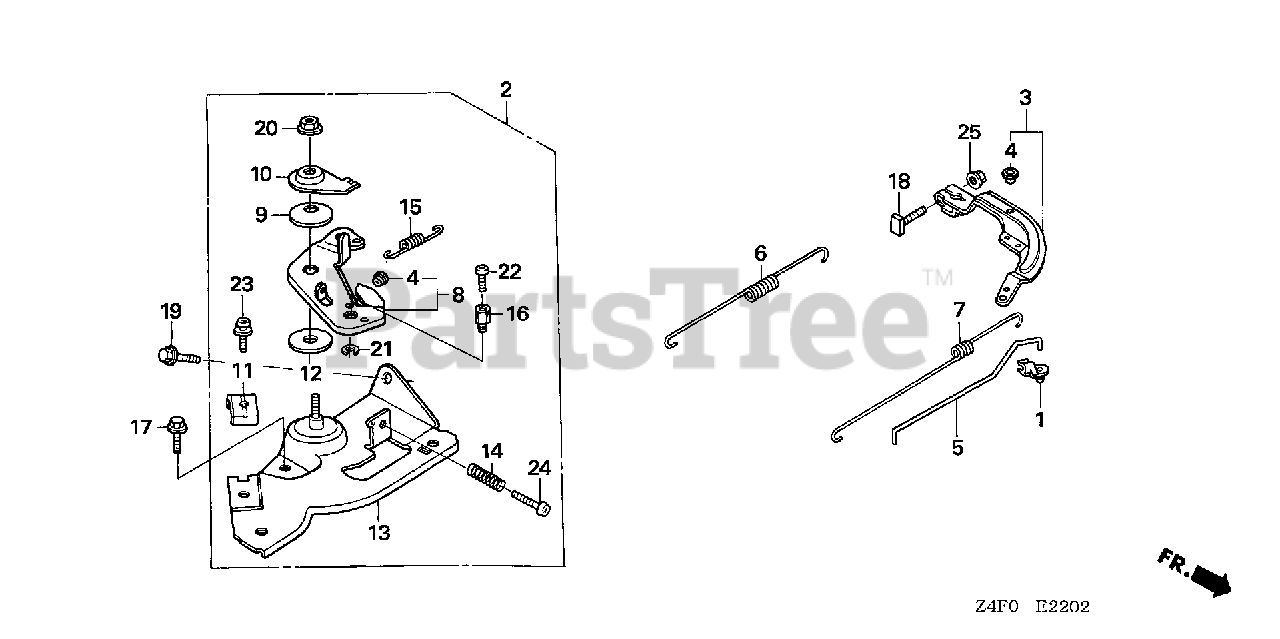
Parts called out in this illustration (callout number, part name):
1	JOINT, ROD
2	CONTROL ASSY.
3	ARM, GOVERNOR
4	COLLAR, LEVER
5	ROD, GOVERNOR
6	SPRING, GOVERNOR
7	SPRING, THROTTLE RETURN
8	LEVER, CONTROL
9	SPRING, LEVER
10	WASHER, CONTROL LEVER
11	HOLDER, CABLE
12	SPACER, CONTROL LEVER
13	BASE, CONTROL
14	SPRING, CONTROL ADJUSTING
15	SPRING, CABLE RETURN
16	HOLDER, WIRE
17	BOLT, FLANGE (6X12) (CT200)
18	BOLT, GOVERNOR ARM
19	BOLT, FLANGE (6X20) (CT200)
20	NUT, SELF-LOCK (6MM)
21	CIRCLIP (5MM)
22	SCREW, PAN (4X6)
23	SCREW, PAN (5X16)
24	SCREW, PAN (5X25)
25	NUT, FLANGE (6MM)
